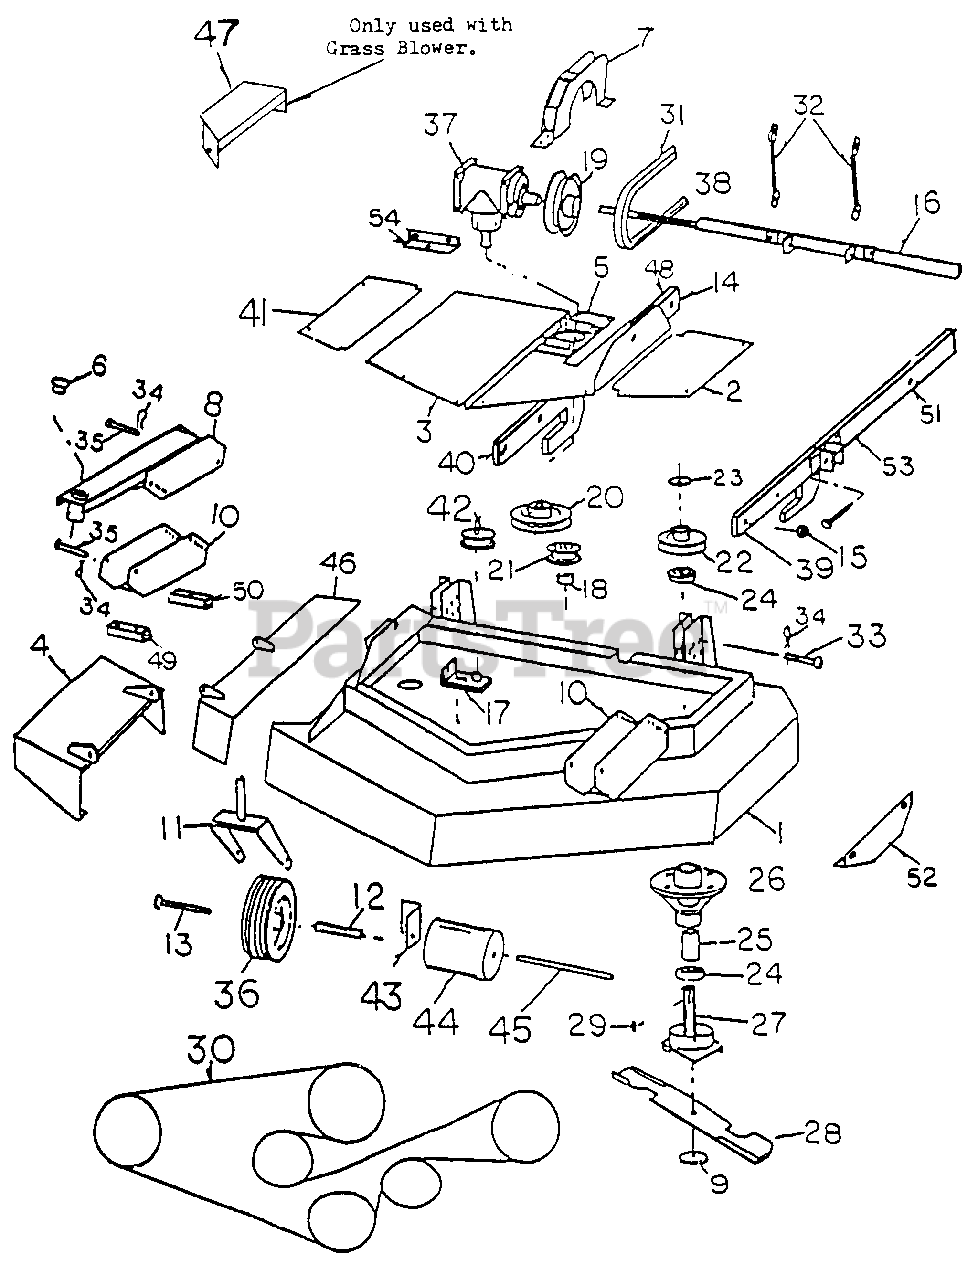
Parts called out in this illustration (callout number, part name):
2	Cover
3	Cover
5	Gear Box Mount
6	Gage Wheel Bushing
8	Gage Wheel Mount
10	Bracket, Gage Wheel Mount
11	Fork, Gage Wheel
12	Axle, Gage Wheel
13	Gage Wheel Bolt
14	Deck Lift Arm Back Adjustable
15	Bushing, Deck Lift Arm
17	Belt Tightener
18	Spacer, Idler
19	Pulley, Gear Box
20	Pulley, Gear Box
21	Pulley, Idler
22	Pulley, Spindle
23	Washer, Spindle
24	Bearing, Spindle
25	Spacer, Spindle
26	Housing, Spindle
27	Shaft, Spindle
28	Blade
29	Key, Spindle
35	Pins, Gage Wheel
38	Cross Bar Pin
39	L.H.1 Deck Lift Arm Front Adjustable
40	R.H.1 Deck Lift Arm Front Adjustable
41	Cover, Right Hand Side
42	Pulley, Idler
43	Rollar Bracket
46	FOOT CUARD 0 MOUNT
47	Cover, Deck Blower Pulley
48	RH.1 Deck Lift Arm Back Adjustable
49	Gage Wheel Bracket Spacer 2 Hole
50	Gage Wheel Bracket Spacer 1 Hole
51	LH.1 Deck Lift Arm Back Adjustable
52	Shoe, Left Hande Side
53	LH.1 Deck Lift Arm Back Adjustable
54	Gearbox Mount Angle
